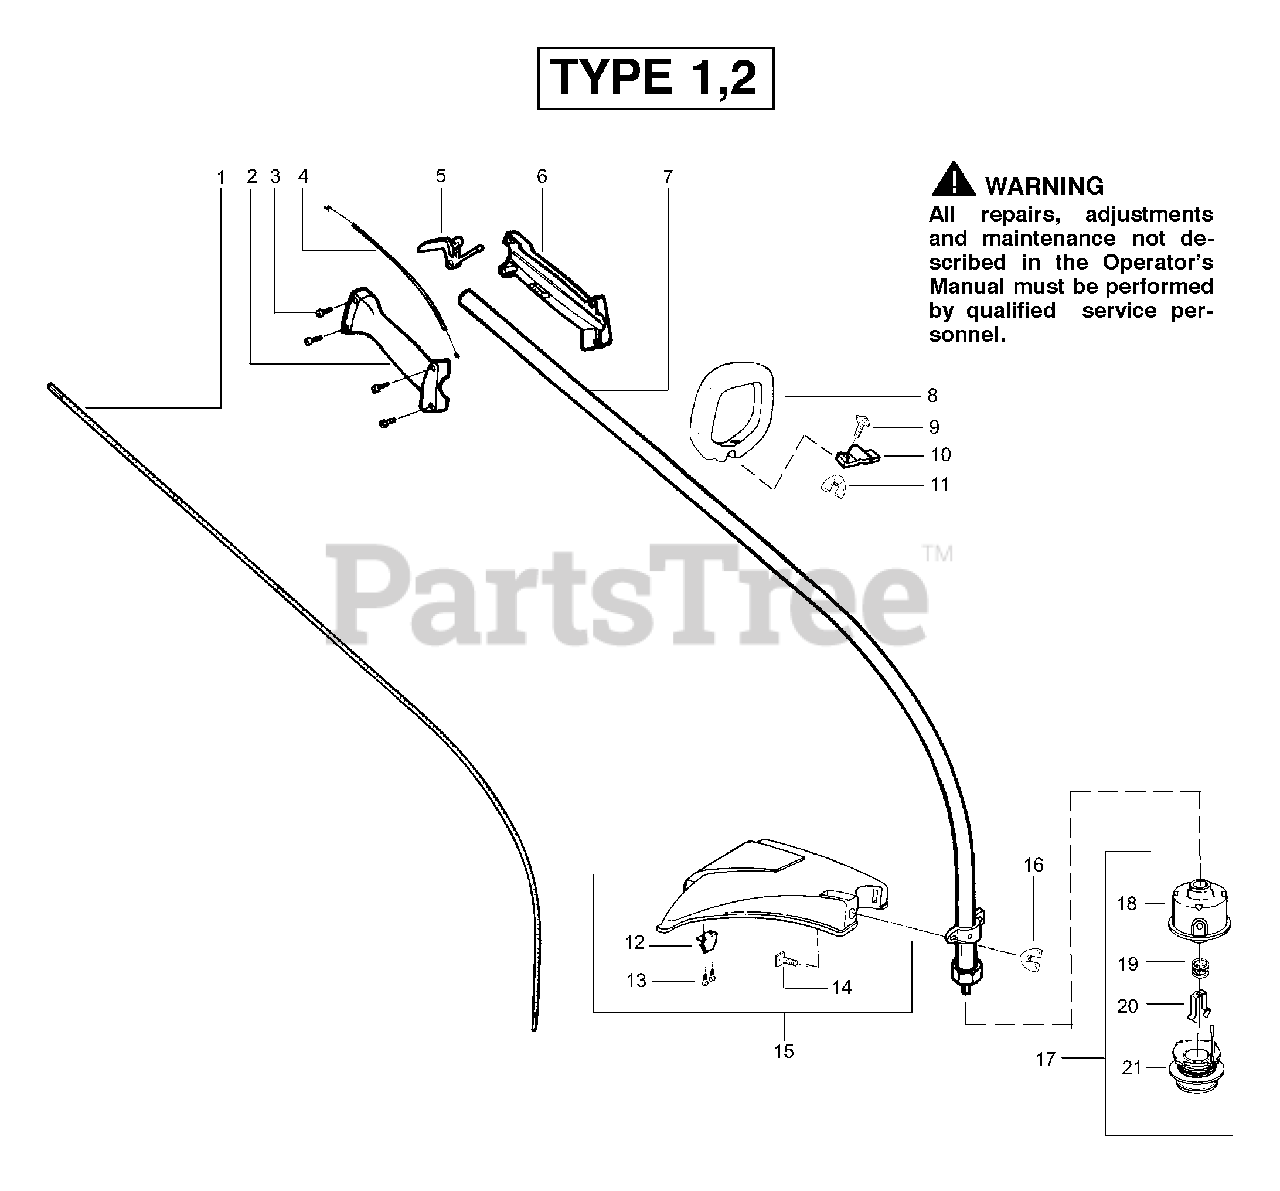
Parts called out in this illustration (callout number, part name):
1	Shaft-Flex
2	Throttle Hsg. (Right)
3	Screw-Throttle Hsg.
4	Assy-Throttle Cable
6	Throttle Hsg. (Left)
7	Assy-Drive Shaft Hsg.
8	Handle-Assist
9	Bolt-Handle/Shield
10	Clamp-Handle
11	Wingnut-Handle/Shield
12	Line Limiter
13	Screw-Line Limiter
14	Bolt-Handle/Shield
15	Kit-Shield Assy
16	Wingnut- Handle/Shield
17	Accy-W/E TNG 5 Cutting Head
18	Assy-Hub
19	Spring- Compression
20	Clip-Retainer- Head
21	Accy- W/E Spool w/Line
